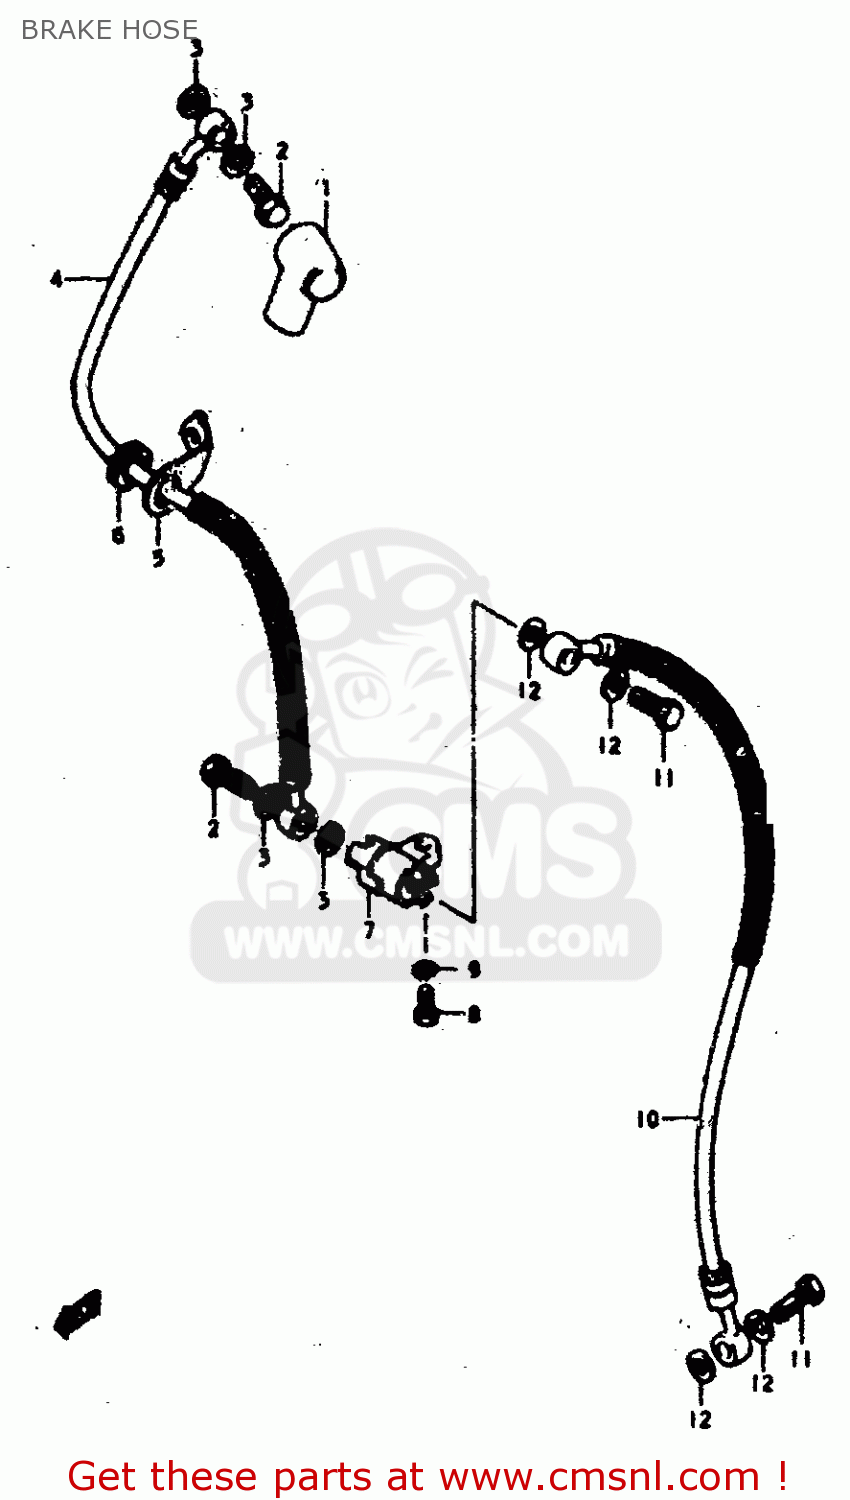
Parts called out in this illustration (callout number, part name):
1	BOOT,MASTER CYLINDER
2	BOLT UNION
3	WASHER
4	HOSE,FRONT BRAKE
5	GUIDE,BRAKE HOSE
6	GROMMET
7	JOINT,BRAKE HOSE
8	BOLT
9	LOCK WASHER
10	HOSE,FRONT BRAKE
11	BOLT UNION
12	WASHER
